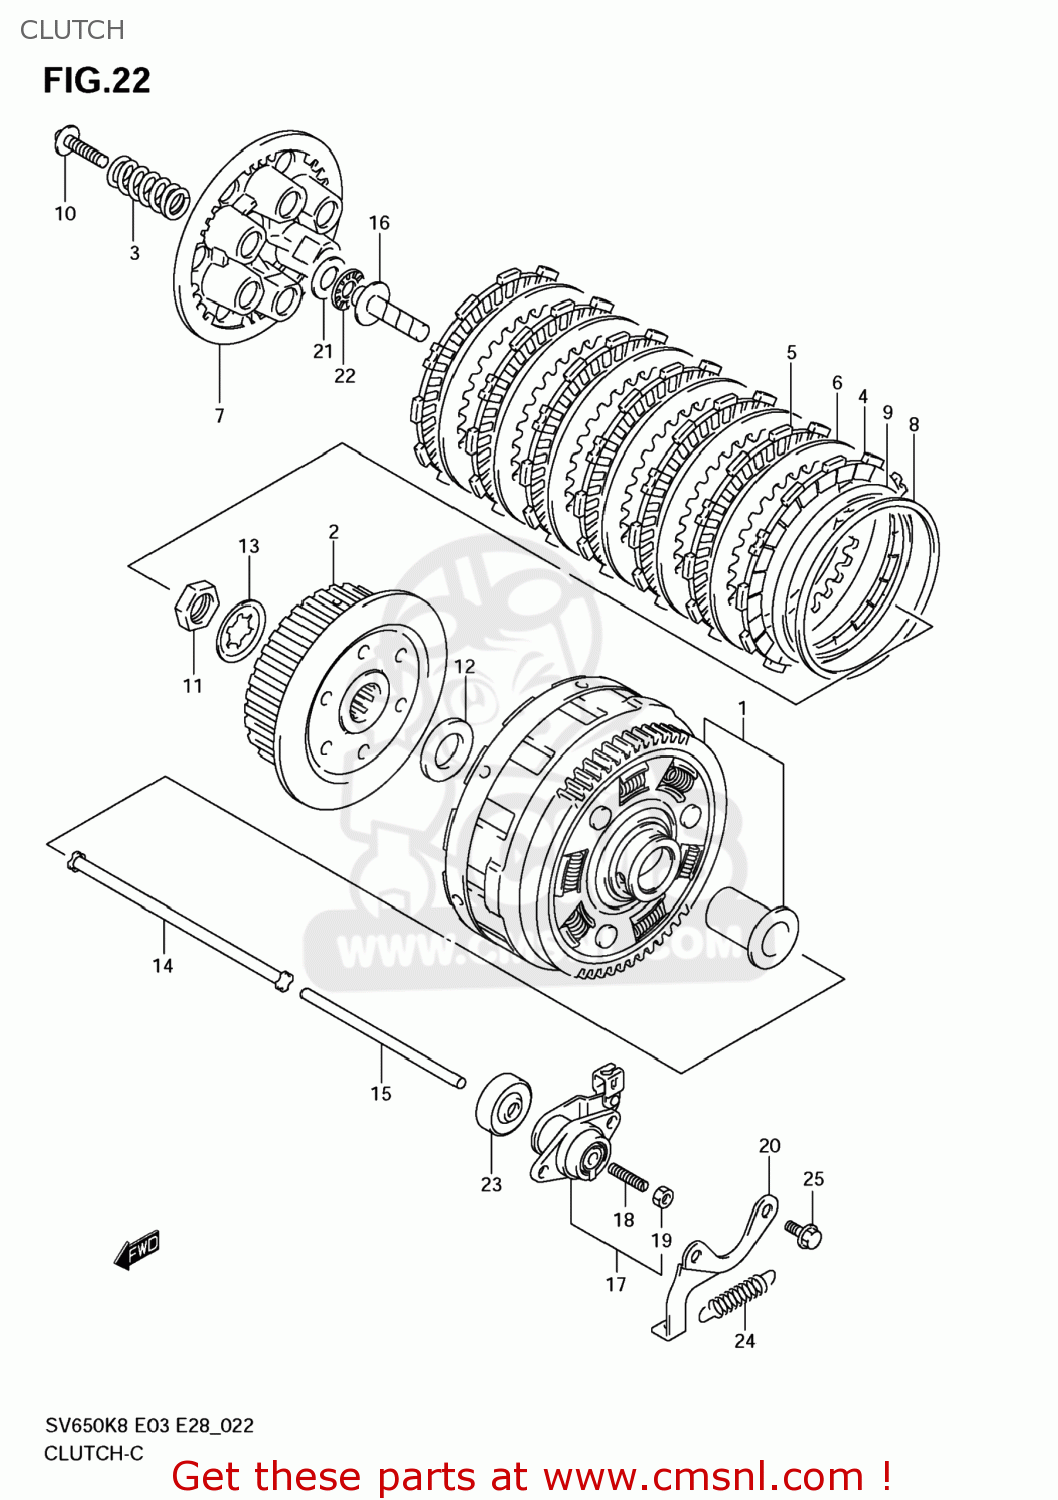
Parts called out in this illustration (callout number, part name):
1	GEAR ASSY,PRI DRIVEN
2	HUB,CLUTCH SLEEVE
3	SPRING,CLUTCH
4	PLATE,CLUTCH DRIVE NO.2 (NAS)
5	PLATE,CLUTCH DRIVE (NAS)
6	PLATE,CLUTCH DRIVEN(T:1.6) (NAS)
7	DISC,CLUTCH PRESSURE
8	SEAT,WAVE WASHER
9	WASHER,CLUTCH PLATE WAVE
10	BOLT(6X30)
11	NUT
12	WASHER(20X36X3)
13	WASHER,LOCK
14	ROD,PUSH,R
15	ROD,CLUTCH PUSH,L
16	PIECE,CLUTCH PUSH
17	SCREW ASSY,CLUTCH RELEASE
18	SCREW(6X25)
19	NUT
20	SUPPORT,CL RLSE RETURN SPRING
21	WASHER(15.5X28X1)
22	BEARING(15X28X2)
23	SEAL,OIL(6X34X5.5)
24	SPRING
25	BOLT
